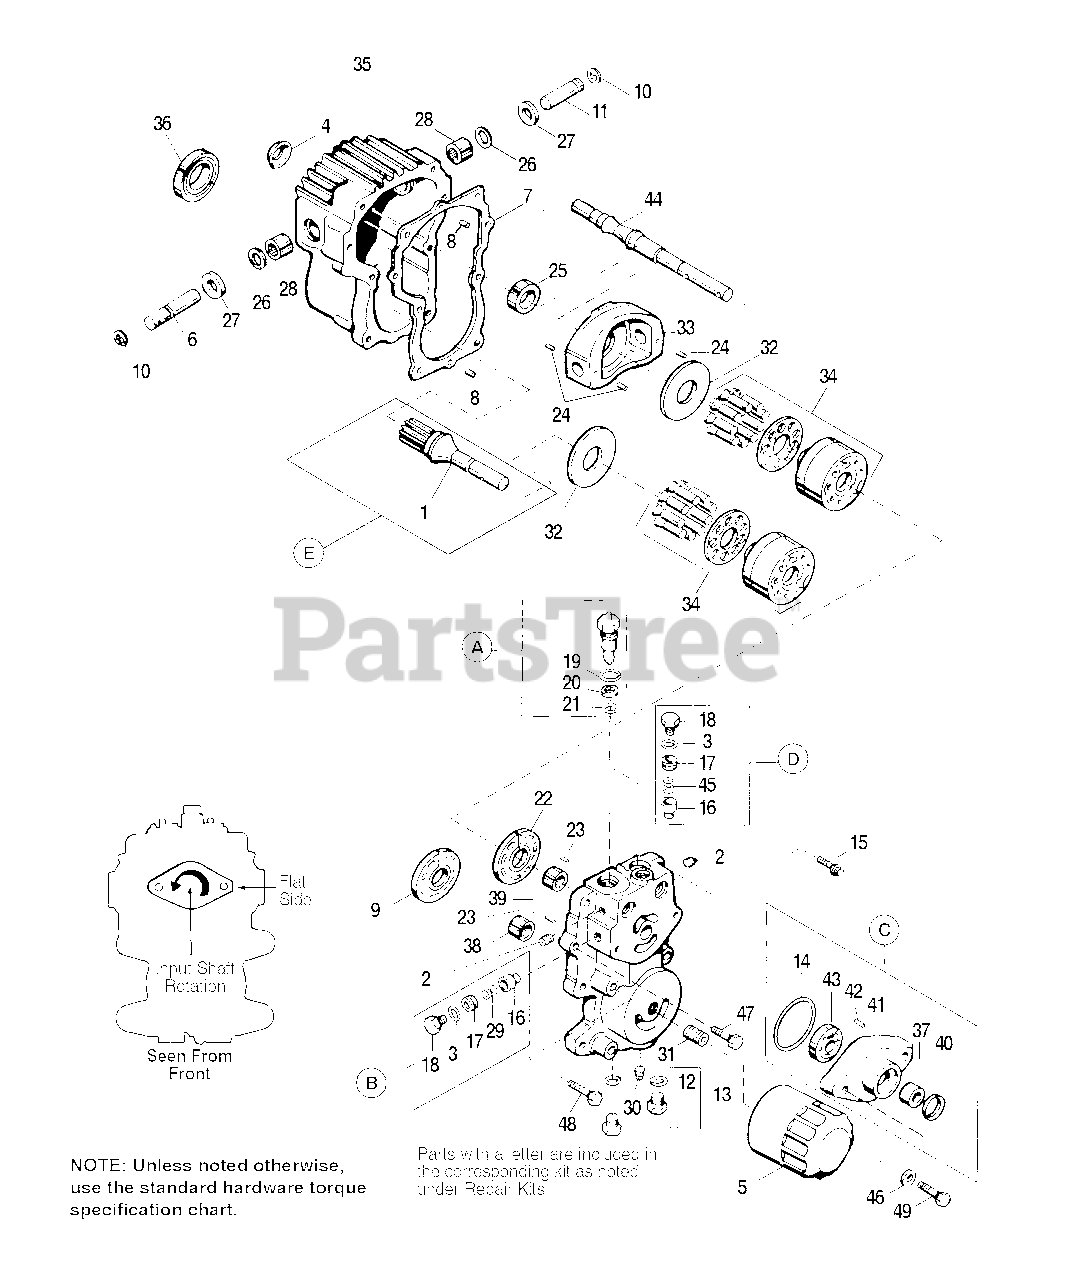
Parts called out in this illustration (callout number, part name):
1	SHAFT, Motor
2	PLUG, Pipe
5	FILTER ASSY.
6	SHAFT, Trunnion
8	PIN, Headless
9	PLATE, Valve (Motor)
10	RING, Retaining
11	SHAFT, Trunnion
13	PLUG, Hex Hd.
15	SCREW, 12 Pt.
16	CONE, Relief Valve
17	KIT, Shim Pack
18	PLUG, Hex Hd.
20	RING, Back-Up
22	PLATE, Valve (Pump)
23	PIN, Headless, St.
24	PIN, Spring
25	BEARING, Ball
28	BEARING, Needle
29	SPRING, Relief Valve
31	UNION, Filter
32	PLATE, Thrust
33	PLATE, Swash
34	BLOCK, Cylinder
35	HOUSING ASSY.
36	BEARING, Ball
37	BEARING, Roller
38	BEARING, Roller
39	SECTION, Center
41	HOUSING, Charge Pump
42	PIN, Straight
44	SHAFT, Pump
45	SPRING, Rel. Valve
46	WASHER, Flat
47	CAPSCREW, Hex Hd., 3/8-16 x 1-1/4
48	CAPSCREW, Hex Hd., 3/8-16 x 2
49	CAPSCREW, Hex Hd., 7/16-14 x 2
A	CHECK VALVE ASSY.
B	RELIEF VALVE KIT
C	CHARGE PUMP KIT
D	RELIEF VALVE KIT
E	SHAFT & SNAP RING KIT
